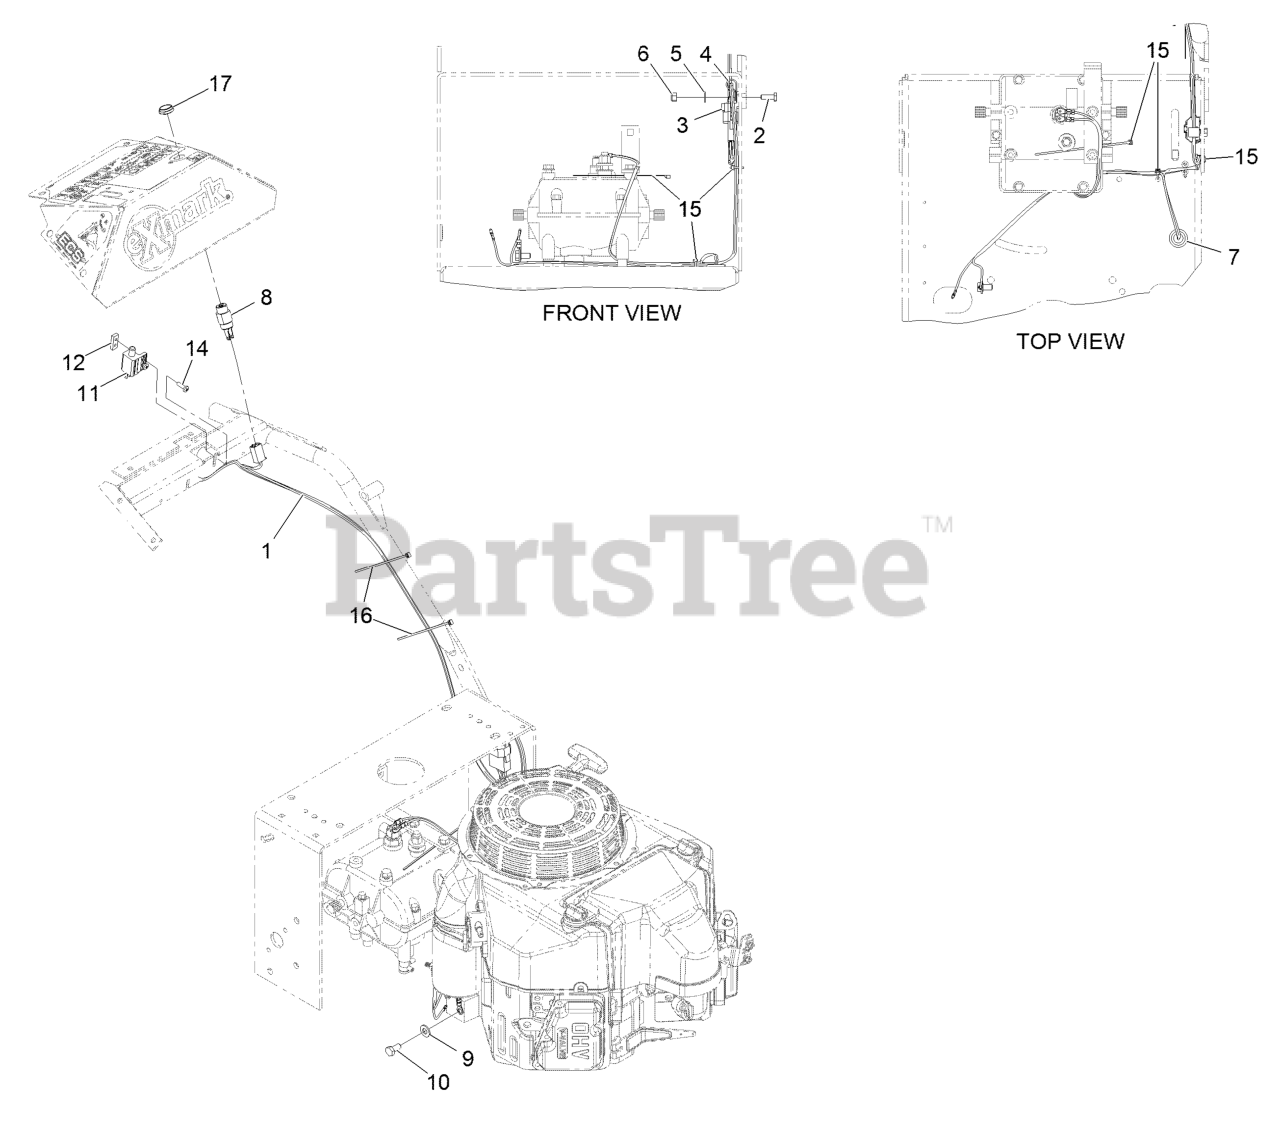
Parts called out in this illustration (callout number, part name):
1	HARNESS-WIRE
2	SCREW-HH
3	MODULE-INTERLOCK
4	CLIP-LOOM
5	WASHER-FLAT
6	NUT-LOCK, NI
7	GROMMET
8	SWITCH & KEY (INCLUDES NU
9	WASHER-PLAIN
10	SCREW-HH
11	SWITCH-OPEN, NORMALLY
12	PLATE-TAPPED
14	SCREW-PPH
15	TIE-CABLE
16	TIE-CABLE
17	NUT-SWITCH, IGNITION
